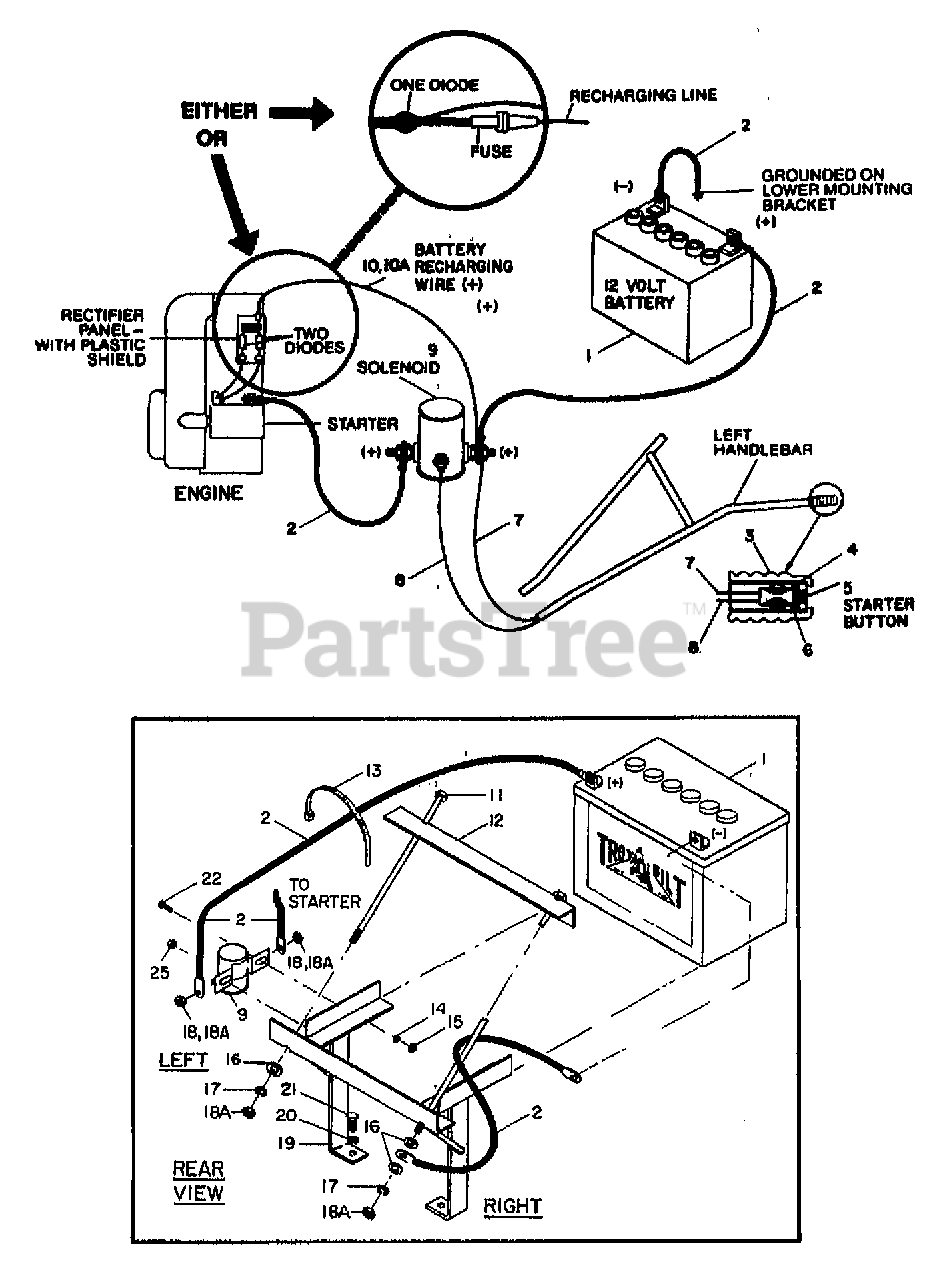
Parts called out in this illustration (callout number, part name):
1	KIT-VENTED BATTERY
2	CABLE-BATTERY
3	GRIP-HANDLEBAR
4	SPACER-1.25X1X1.375
5	SWITCH-STARTER
6	WASHER-#1.25X.938X.062
7	ASSM-WIRE LG
8	ASSM-WIRE SM
9	KIT-SOL W/HDW
10	ASSEMBLY-CONNECTOR
10A	ASSM-WIRE SOL/RECTIFIER
11	SCR-HH 5/16-18 X 9
12	CLAMP-BATTERY BRKT
13	TIE-RED
14	WASHER-LK .25 ZP
15	NUT-HEX 1/4-20 ZP
16	WASHER-FLAT 5/16 SAE
17	WASHER-LK .312 ZP
18	NUT-HEX 5/16-24
18A	NUT-HEX 5/16-18 ZP
19	KIT-BATTERY BRKT HORSE
20	WASHER-LK .375 @ DEPL
21	BOLT-HH 3/8-16X1.5 FTH ZP
22	SCR-RH 1/4-20 X .75 ZP
23	CLIP-SPECIAL
25	NUT-HH M10-32X.125
